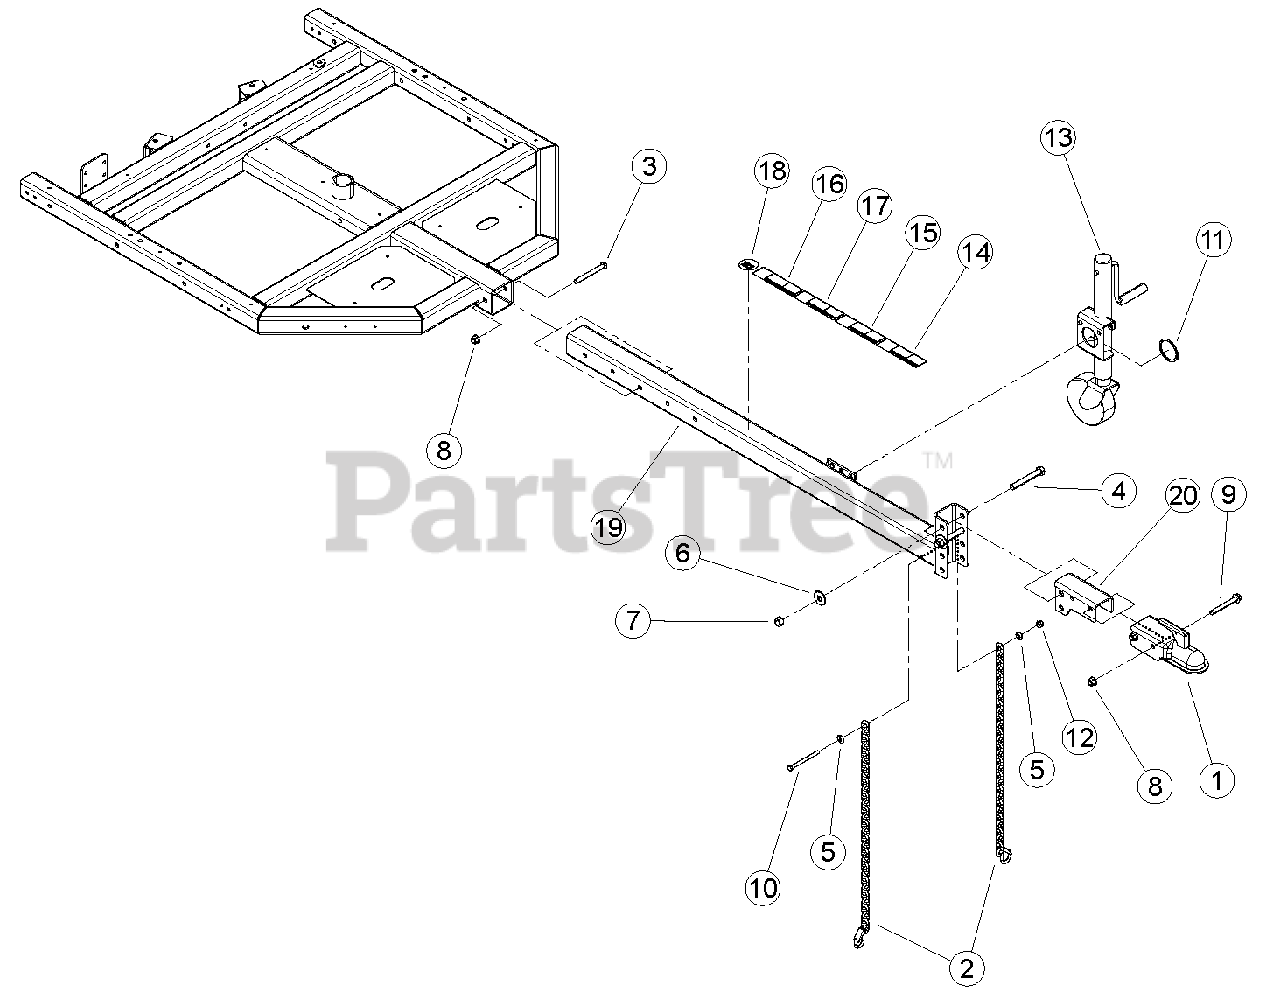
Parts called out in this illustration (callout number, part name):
1	COUPLER, 2 IN
2	CHAIN, SAFETY 5,000 LB W/ LATCH
3	BOLT, 1/2 X 4-1/2" GR5 HHCS NC ZP
4	BOLT, 5/8 X 4-1/2 HEX HD G5 ZP
5	WASHER, 3/8" FLAT ZP
6	WASHER, 5/8" FLAT ZP
7	NUT, 5/8" CENTERLOCK ZP GR5
8	NUT, 1/2-13 NYLOCK FLANGE
9	BOLT, 1/2-13 X 4 HWH GR5 CZP
10	BOLT, 3/8 X 4-1/2" HHCS GR5 NC ZP
11	SNAP RING, 2-1/2 EXTERNAL
12	NUT, 3/8-16 NYLOCK FLANGE
13	JACK, PIVOTING W SWIVEL CASTOR
14	DECAL, SAFETY CHAINS
15	DECAL, TRAILER ELECTRICAL
16	DECAL, CHECK WHEELS
17	DECAL, SAFE COUPLING
18	DECAL, NATM COMPLIANCE
19	WELDMENT, HITCH POLE W/ PLATE
20	MOUNT, COUPLER
